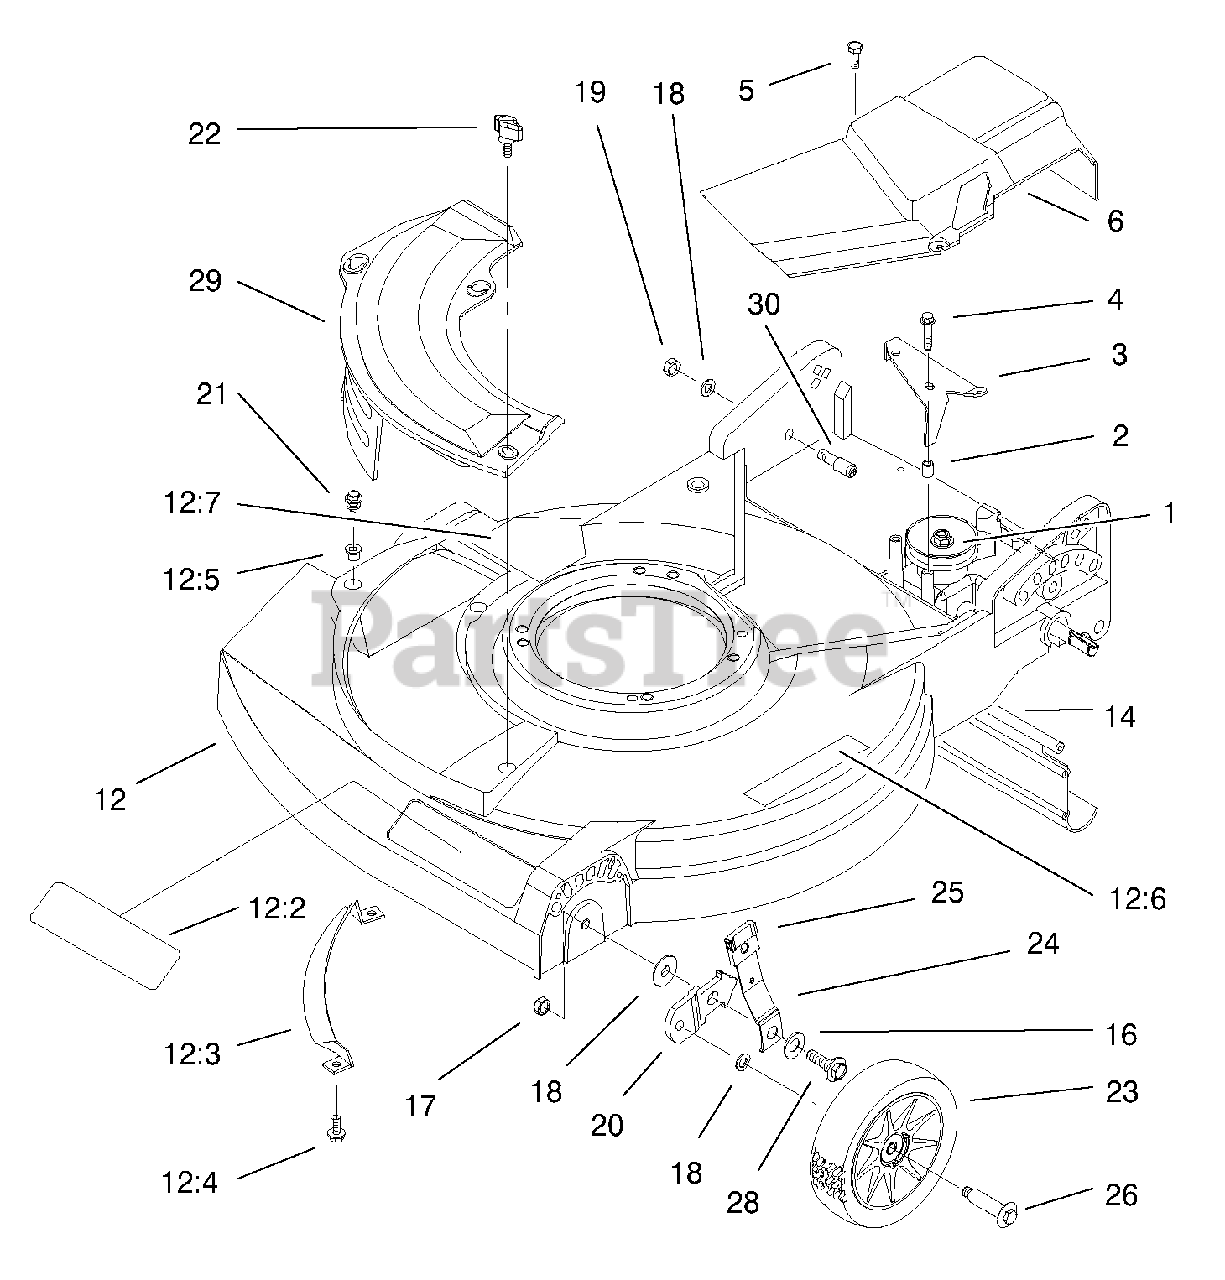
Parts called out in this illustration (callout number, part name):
1	Gear Case ASM
3	Bracket-Actuator
4	Screw-HWH
6	Cover-Drive
12:2	Decal-Deck
12:3	Toe Bar
12:4	Screw-HWH
12:5	Grommet-Plastic
12:6	Decal-Warning
12:7	Decal-Danger
14	Shield-Trailing
16	Washer-Belleville
17	Nut-Lock, NI
20	Bracket-Wheel Height Adjustment
21	Screw-Sems
23	Wheel & Tire ASM
24	Spring Arm ASM-Front
25	Knob-Lever, Height Adjustment
26	Bolt-Shoulder
28	Bolt-Shoulder
29	Plate-Mulch
30	Screw-Torx
